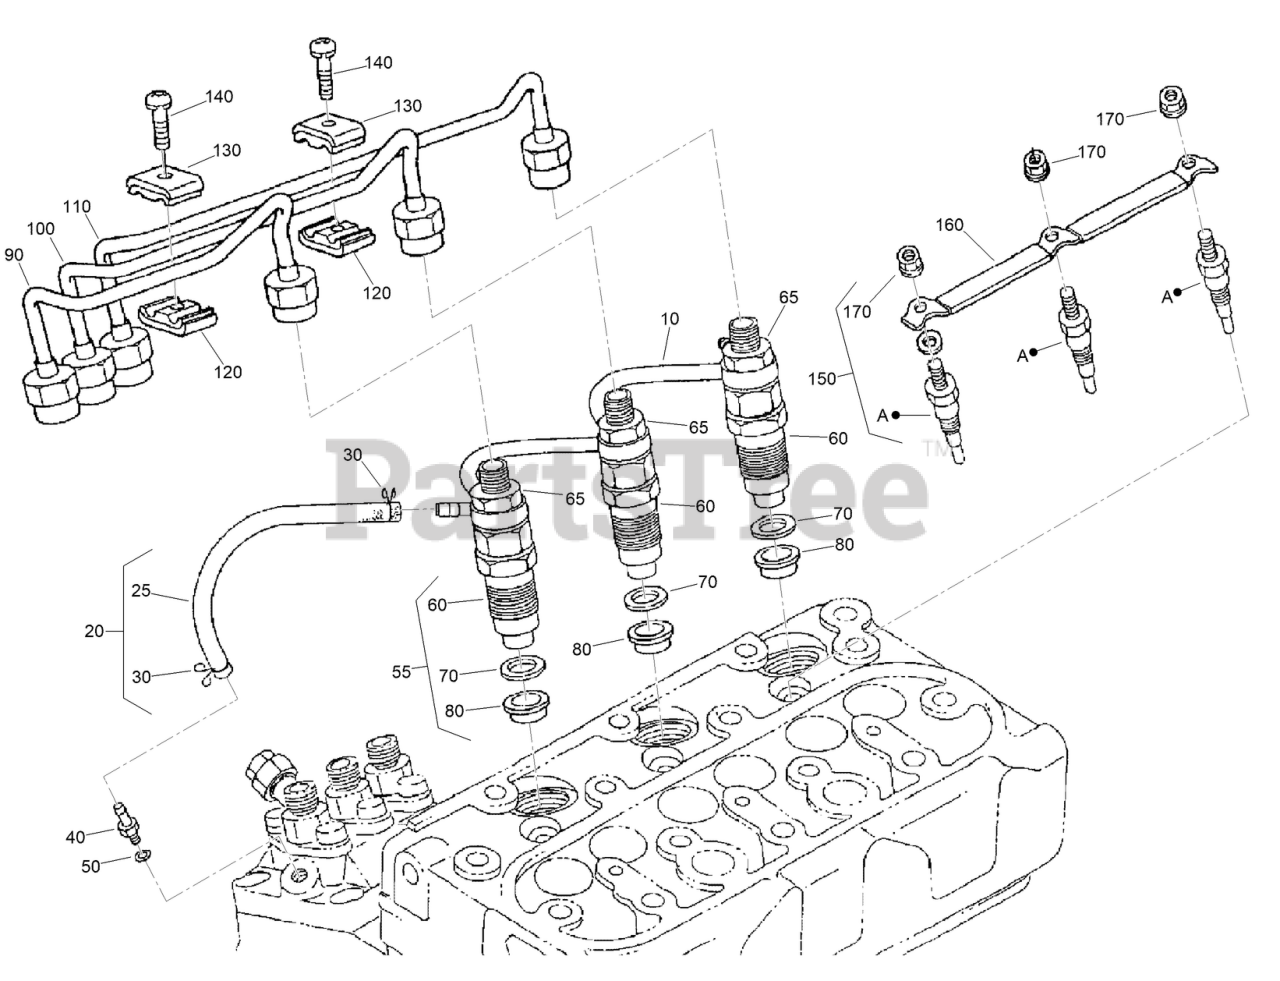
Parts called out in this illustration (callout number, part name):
10	OVER FLOW PIPE ASM
20	OVERFLOW PIPE ASM
25	PIPE-OVERFLOW
30	CLIP-PIPE
40	SCREW-BLEEDER, AIR
50	GASKET
55	NOZZLE HOLDER KIT
60	NOZZLE HOLDER ASM
70	GASKET
80	SEAL-HEAT
90	PIPE-INJECTION
100	PIPE-INJECTION
110	PIPE-INJECTION
120	CLAMP-PIPE
130	CLAMP-PIPE
140	SCREW (W/WASHER)
150	PLUG-GLOW
160	CORD-PLUG, GLOW
170	NUT-FLANGE
